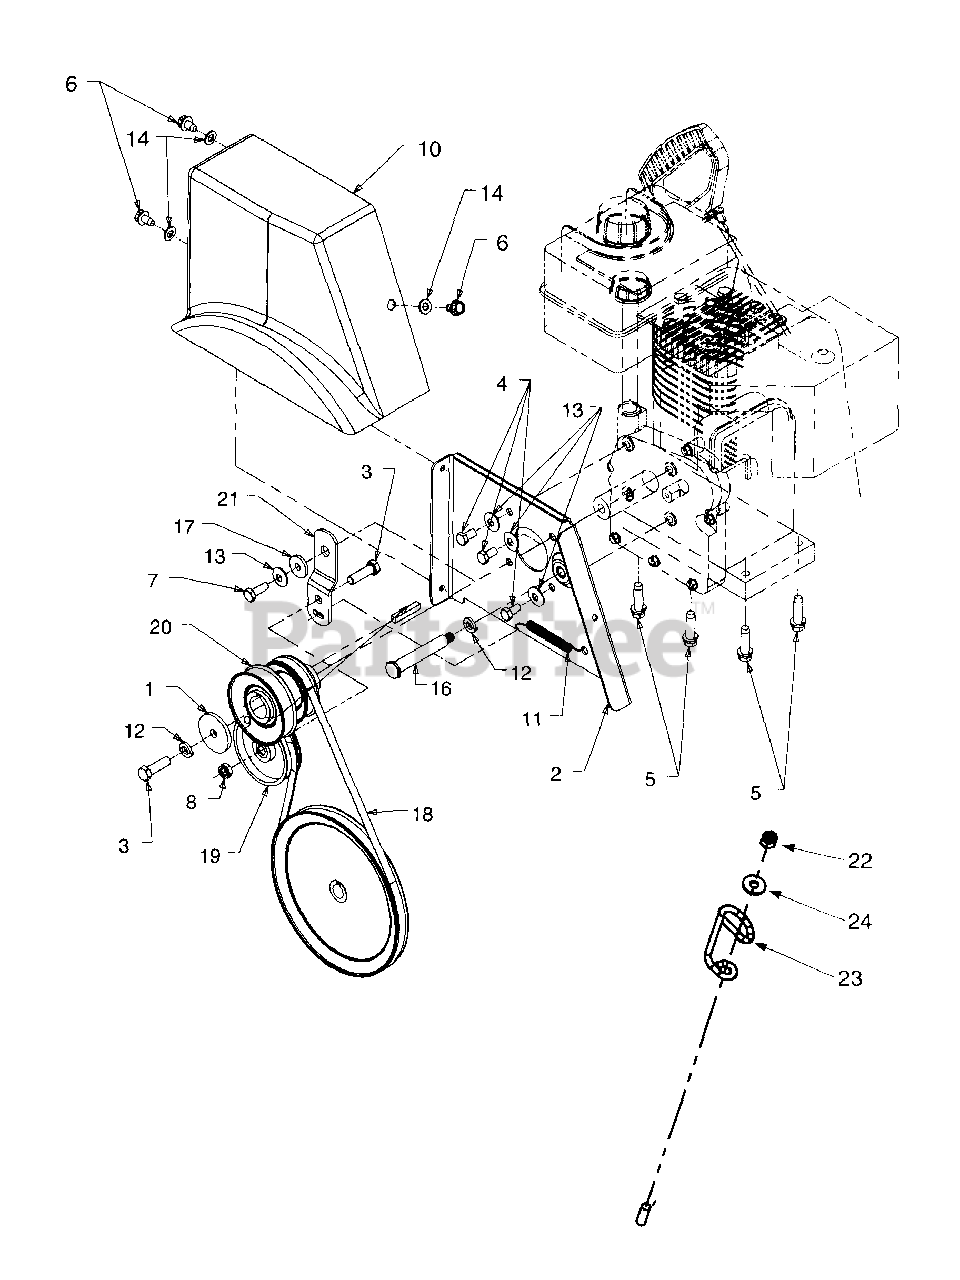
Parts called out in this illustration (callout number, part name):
1	Washer .390 I.D. x 1.75
2	Brkt Asm:Cvr:Belt
3	Hex Head Screw
4	Hex Hd. Screw 5/16-24 x .625
5	Hex TT-Tap Scr. 3/8-16 x 1 .25" Lg.
6	Hex Wash. Screw 5/16-18
7	Hex Lock Screw 5/16-24 x .875
8	Jam Nut 3/8-24 Thd.
10	Belt Cover
11	Spring: Extension
12	L-Wash. 3/8
13	Bell-Wash. .340 I.D. x .872 O.D.
14	Fl-Wash. .330 I.D. x .630 x .06
16	Shld. Screw .498 x 2.99 Lg.
17	Shld. Spacer
18	Variable Speed Belt
19	Fl-Idler Pulley 3.0" Dia.
20	Double Pulley
21	Idler:Brkt
22	Hex Lock Nut 1/4-20
23	Cable Control Wire
24	Fl-Wash. .28 x .74 x .063
